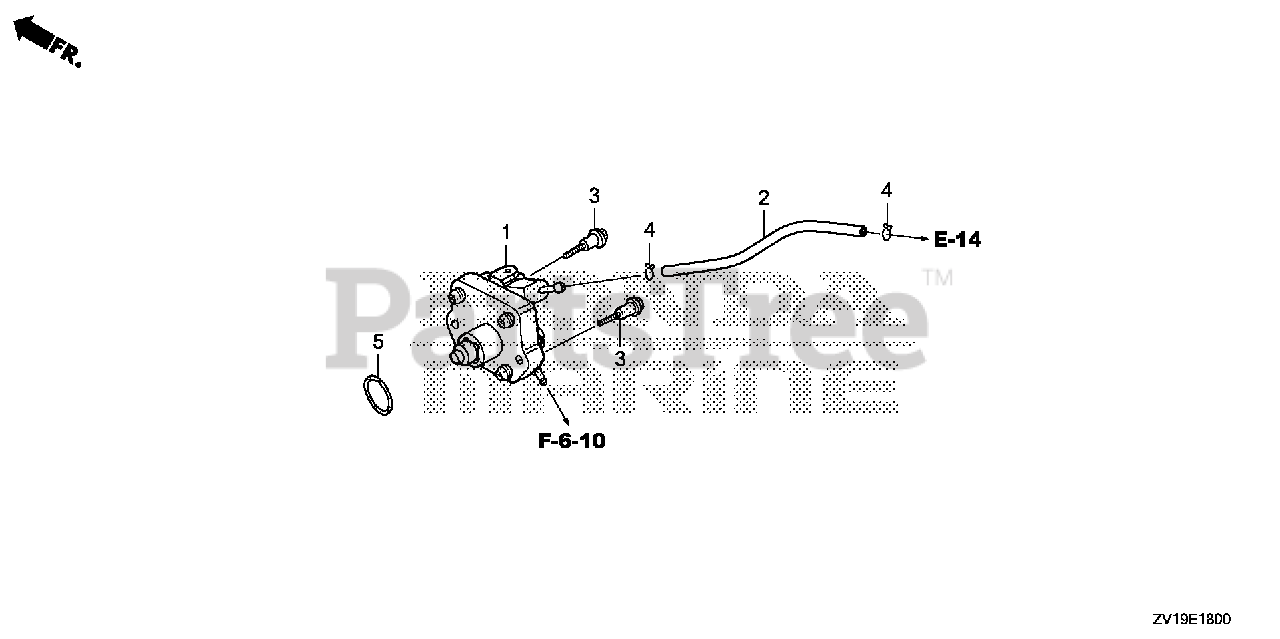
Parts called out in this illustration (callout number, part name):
1	PUMP ASSY., FUEL (MSDS)
2	TUBE C, FUEL
3	BOLT, SPECIAL (6X34)
4	CLIP, TUBE (B8)
5	O-RING (20.8X2.4)
